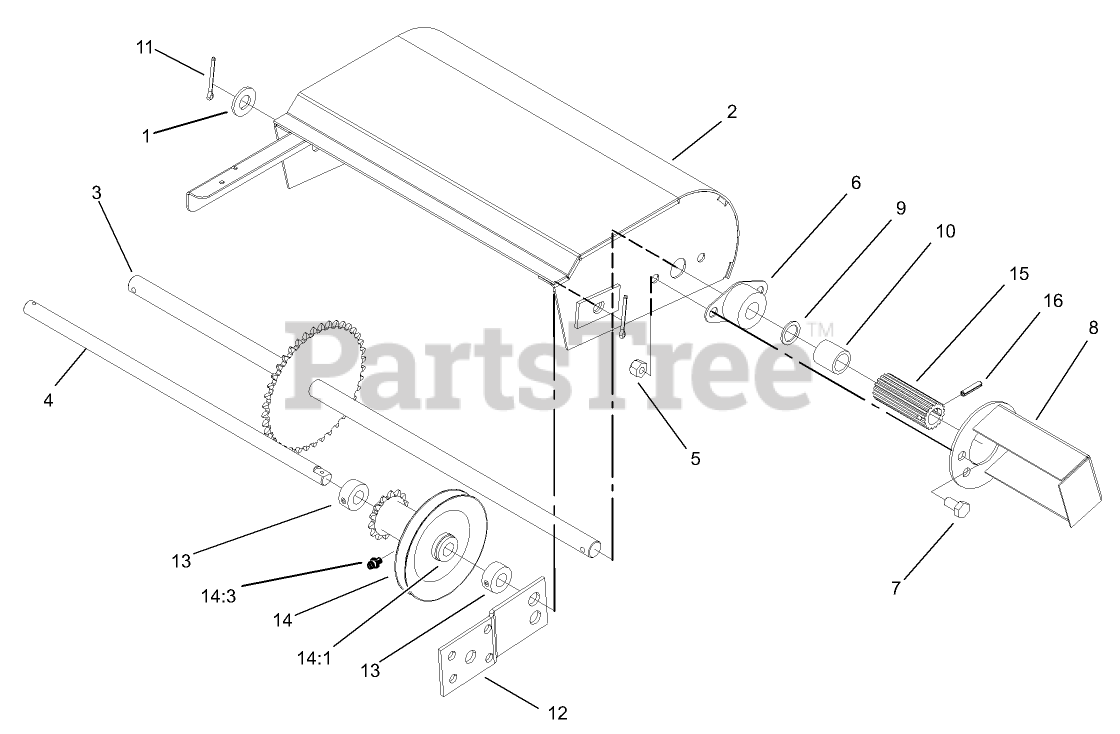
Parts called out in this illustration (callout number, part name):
1	WASHER-FLAT
3	SHAFT-WHEEL, FRICTION
4	SHAFT-IDLER
5	NUT-LOCK, NI
6	BEARING-MOUNT, FLANGE
7	SCREW-HH
9	WASHER
10	SPACER
11	PIN-COTTER
12	BRACKET-MOUNTING
13	COLLAR
14	IDLER ASM
14:1	BUSHING-FLANGE
14:3	FITTING-GREASE
15	WHEEL-FRICTION
16	PIN-ROLL, SLOTTED
